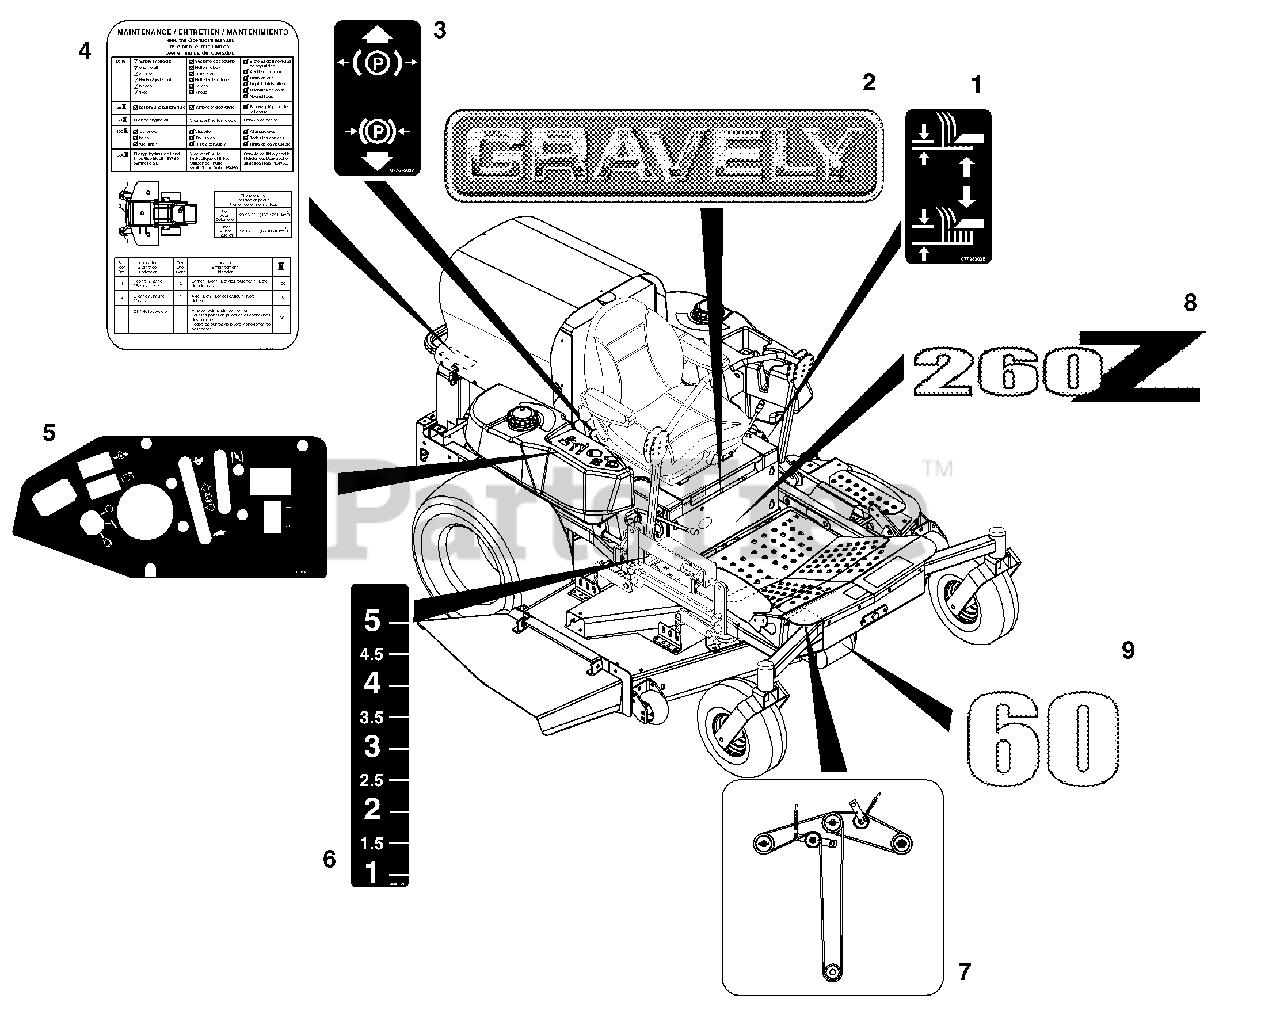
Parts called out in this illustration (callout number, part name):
1	Decal, Lift Lever
2	Decal, 15" Gravely Logo
3	Decal, Parking Brake Lever
4	Decal, Service Instructions
5	Decal, Gas Control Panel
5	Decal, Diesel Control Panel
6	Decal, Height of Cut
7	Decal, Belt Diagram
8	Decal, PM-260Z
8	Decal, PM-272Z
9	Decal, 60
9	Decal, 72
